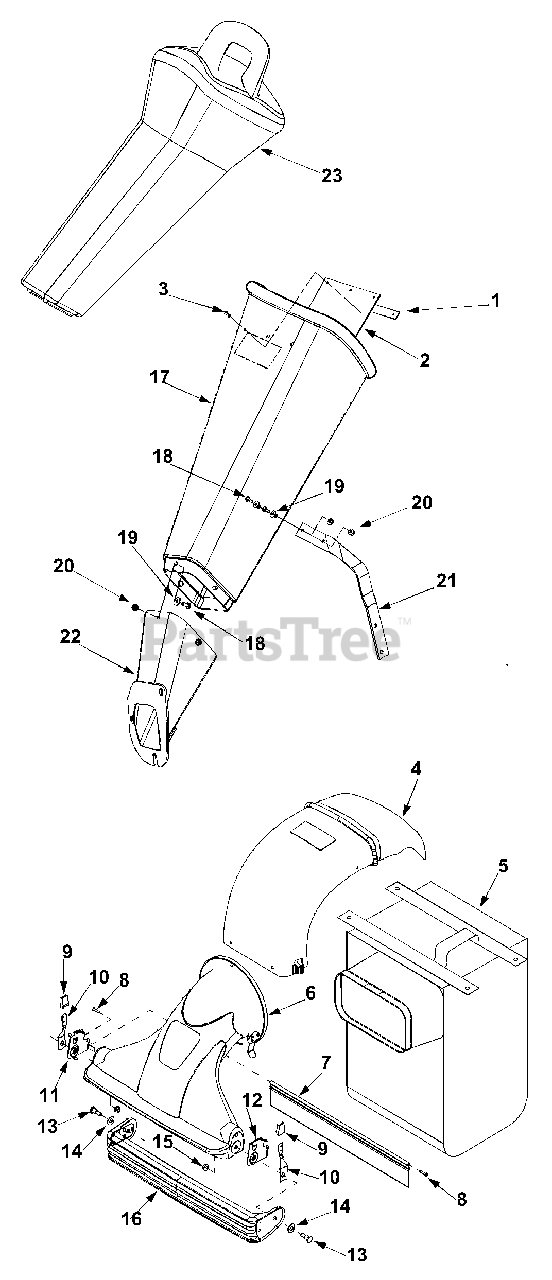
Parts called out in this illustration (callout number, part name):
1	Chute Flap Strip
2	Chute Flap
3	Pop Rivet
4	Discharge Chute
5	Bag
6	Nozzle Assembly
7	Nozzle Flap
9	Height Adjustment Knob
10	Spring Lever
13	Shoulder Screw
14	Flat Washer .510 x 1.12 x .060
15	Hex Flange Lock Nut 3/8-16
16	Door Assembly
17	Chipper Chute
18	Hex Cap Screw 1/4-20 x .620
19	Flat Washer .28 ID x .74 OD
20	Hex Lock Nut 1/4-20
